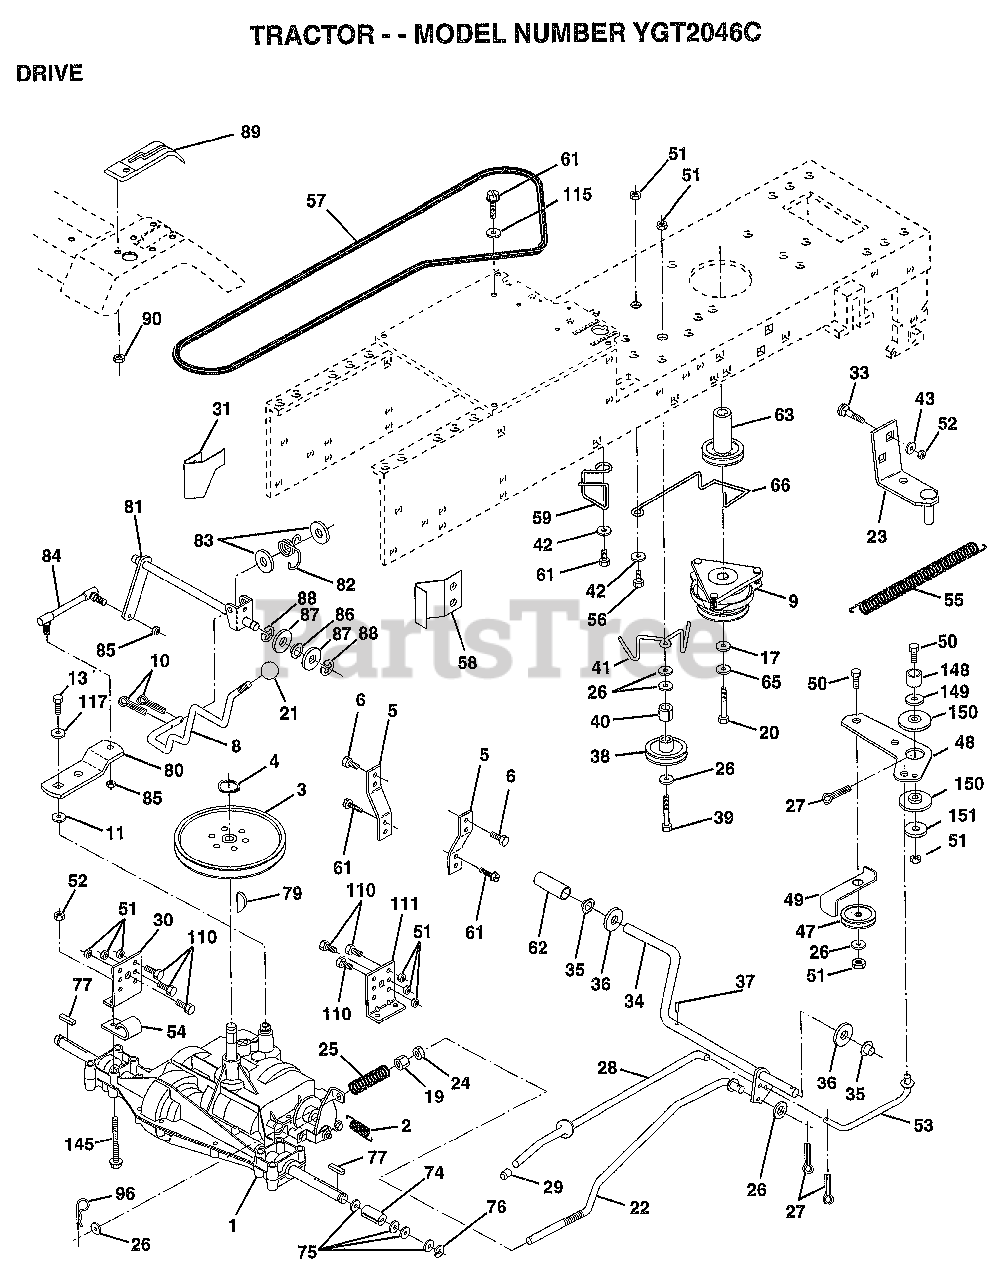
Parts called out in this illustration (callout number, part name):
3	PULLEY TRANSAXLE
4	RING
5	STRAP TORQUE
6	SCREW
8	ROD SHIFT FEND YT
10	PIN COTTER 1/8
11	WASH-SHFT PLT LT
13	BOLT.1/4-28.W/PAT
17	WASHER
19	NUT
20	BOLT.7/16-20X4.25
21	KNOB.DUCKHEAD.1/2
22	ROD.ASM.BK.44.MWR
23	BRACKET.ASM.MTG
24	NUT
25	"SPRING,ROD BRAKE"
26	WASHER
27	COTTER PIN
28	ROD.BRAKE.PARK.LT
29	PLUNGER CAP T
30	BRKT TRANS LH
31	KEEPER BELT LH
33	BOLT
34	SHAFT ASM-PEDAL F
35	NYLON BEARING
36	WASHER LT
38	PULLEY.IDLER.FLAT
39	BOLT
40	SPACER T
42	WASHER
43	WASHER T
48	BELLCRANK.CLUTCH
49	RETAIN BELT
53	"LINK, CLUTCH T"
54	"CLIP,INSULATOR"
55	"SPRING, RETURN LT"
57	V-BELT.DRIVE
58	"KEEPER,BELT RH"
59	KEEPER BELT CNTSP
61	SCREW
62	"COVER,PEDAL"
63	PULLEY ENGINE
65	LOCKWASHER
66	KEEPER-BELT
74	SPACER HYT
75	WASHER
76	E RING HYT
77	SQ KEY STD
80	"ARM,SHIFT"
81	SHAFT ASM CROSS
82	"SPRING,TORSION"
83	WASHER
84	"ROD LINK,SHIFT AD"
85	NUT.CNT.LOCK.1/4
86	BUSHING
87	WASHER D
88	KLIP RING
89	CONSOLE SHIFTER
90	NUT
111	BRKT TRANS RH
115	WASHER GT
117	WASHER PM
145	BOLT.HEX.FLGHD
149	SPACER RETAINER
150	BUSHING.NYLON
151	WASHER
